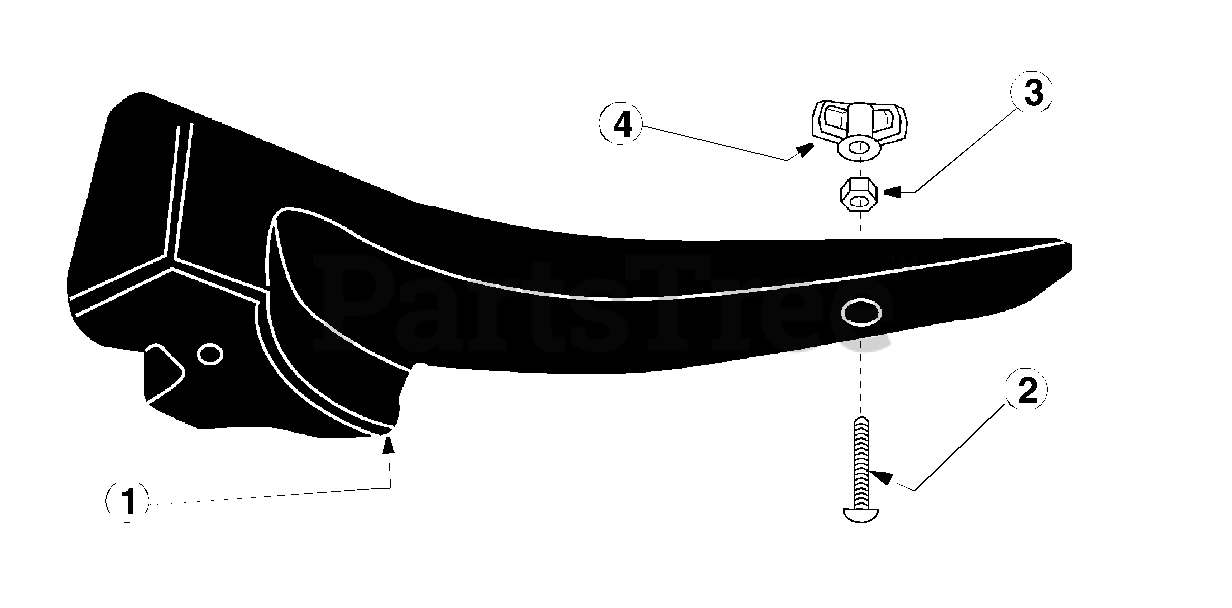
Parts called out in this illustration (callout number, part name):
1	Mulching Plug
2	Machine Screw (1/4")
3	Hex Locking Nut (1/4")
4	Wing Nut (1/4")
